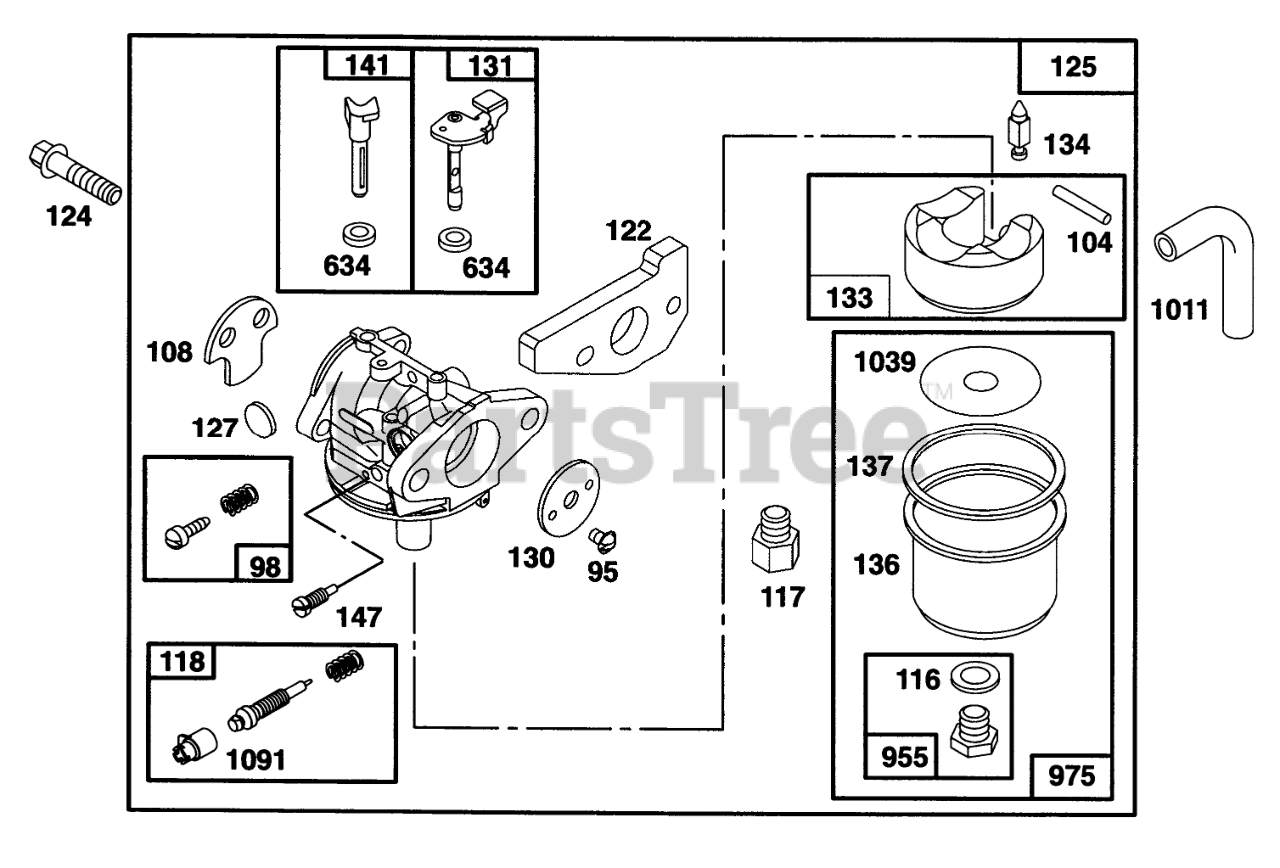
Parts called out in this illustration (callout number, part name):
95	SCREW - ROUND HEAD
98	IDLE ADJUSTING SCREW
104	FLOAT HINGE PIN
108	VALVE - CHOKE
116	SEALING GASKET
117	Jet-Main
118	VALVE/SPRING - NEEDLE
122	ADAPTER ASSEMBLY
124	HEX HEAD SCREW
125	ASSEMBLY - CARBURETOR
127	PLUG - WELCH
130	THROTTLE VALVE
131	THROTTLE SHAFT
133	FLOAT-CARBURETOR
134	Valve-Inlet (Includes Seat)
136	FLOAT BOWL
137	FLOAT BOWL GASKET
141	CHOKE SHAFT
147	JET - PILOT
634	SEAL WASHER
955	HEX HEAD SCREW
975	CARBURETOR BOWL ASM
1011	VENT TUBE
1039	FLOAT LIMITER
1091	CAP - LIMITER
